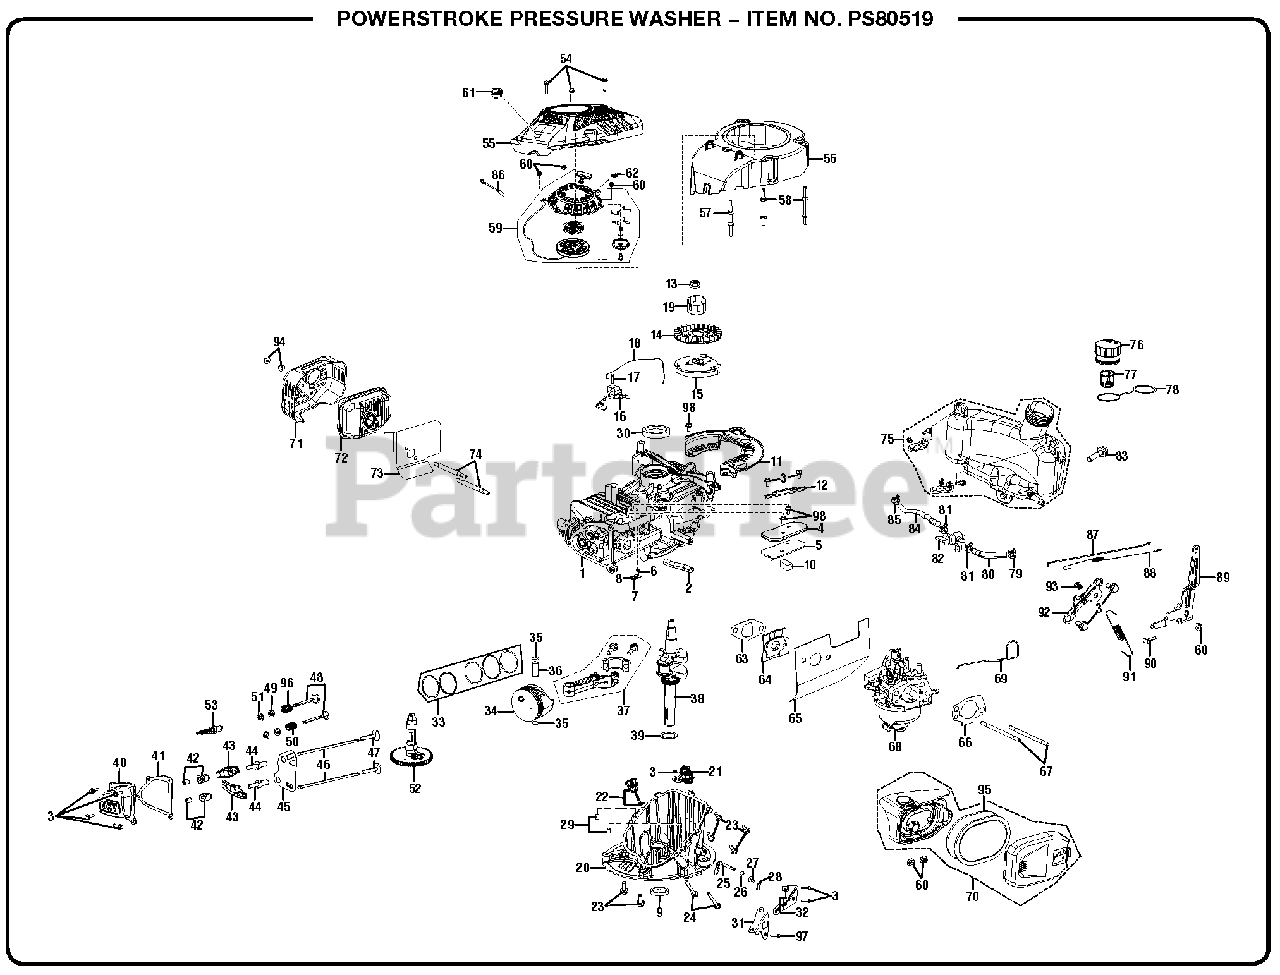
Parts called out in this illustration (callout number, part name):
1	Crankcase Assembly (2014)
4	Breathe Groove Cover Plate
5	Breathe Groove Gasket
6	Bolt (Cross-Stitch)
8	Valve Reed Stopping Plate
10	Breathe Groove Strainer
15	Flywheel Subassembly
18	Ignition Coil Wire
20	Crankcase Cover (2014)
21	Governor Gear Assembly
22	Dipstick Assembly
31	Fuel Valve Holder
33	Oil Ring Set (2014)
35	Piston Pin Clip
37	Connecting Rod (2014)
38	Crankshaft Assembly
40	Cylinder Head Cover
41	Cylinder Head Cover Gasket
42	Valve Adjusting Nut
44	Valve Adjusting Bolt
49	Valve Spring Seat
52	Camshaft Assembly
59	Recoil Starter Assembly (2014)
61	Stop Engine Switch
63	Insulator Plate Gasket
64	Carburetor Insulator Plate
65	Insulator Plate Gasket
66	Carburetor Gasket
68	Carburetor Assembly (2014)
71	Muffler Outer Cover
72	Muffler Assembly (2014)
73	Exhaust Outlet Gasket
76	Fuel Tank Cover
77	Fuel Tank Strainer
78	Fuel Tank Lock Ring
82	Fuel Valve (2014)
86	Stop Engine Switch Grounding Wire
88	Throttle Valve Returning Spring (2014)
89	Governer Support Subassembly
90	Governer Support Bolt
91	Governer Spring
92	Throttle Control Bottom Plate Subassembly
